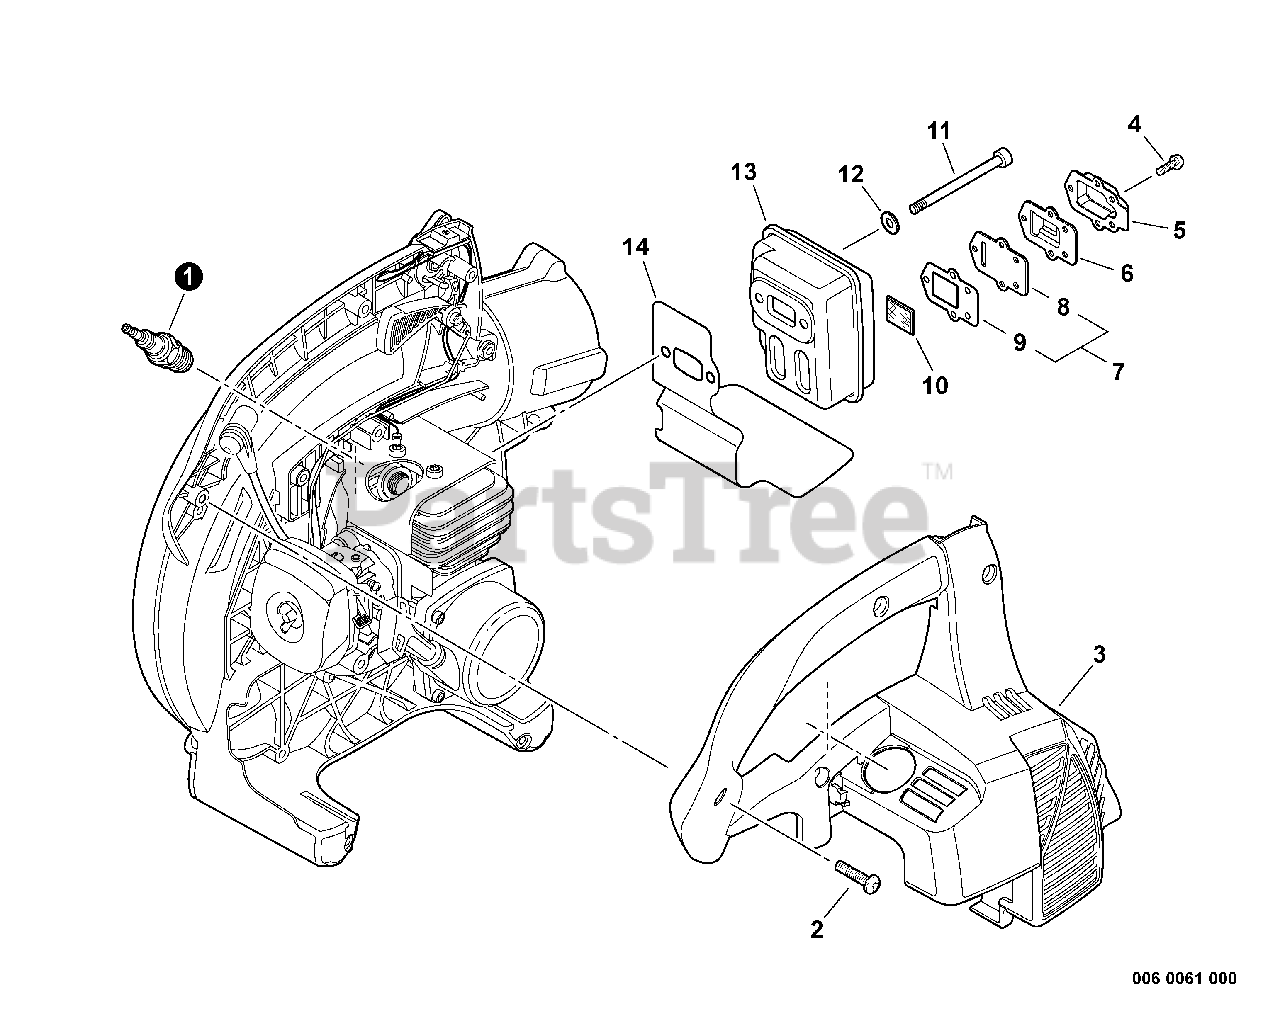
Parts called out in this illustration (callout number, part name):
1	SPARK PLUG - BPM8Y
1	SPARK PLUG - BPMR8Y
2	BOLT, TORX 5×20
3	COVER, ENGINE
4	BOLT, TORX 4×8
5	OUTLET, EXHAUST
6	GUIDE, EXHAUST
7	GASKET KIT, EXHAUST
8	GUIDE, EXHAUST
9	GASKET, EXHAUST
10	SCREEN, SPARK ARRESTER
12	WASHER 5.5×12×0.8
13	MUFFLER
14	HEAT SHIELD, EXHAUST
